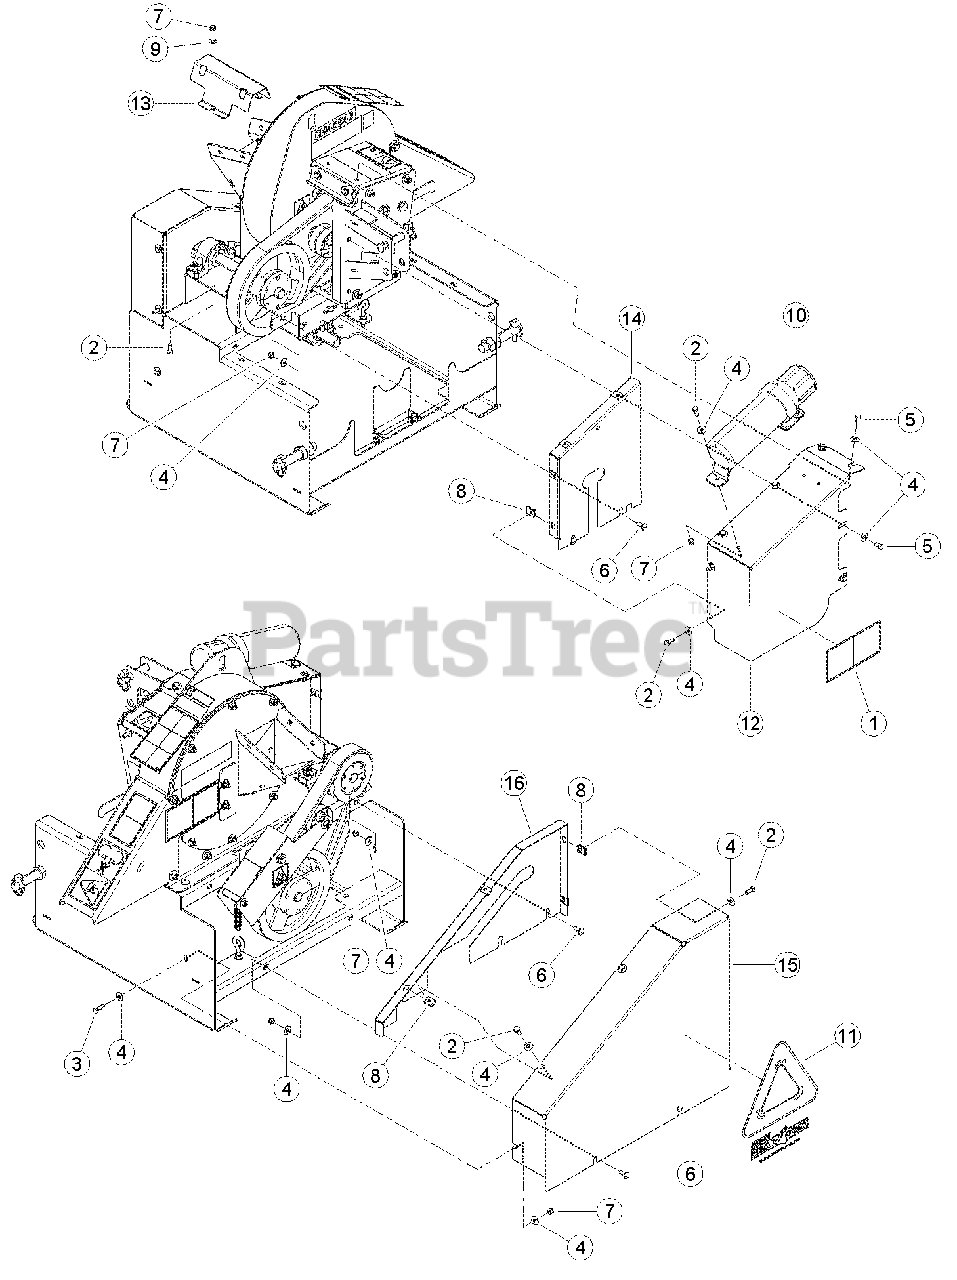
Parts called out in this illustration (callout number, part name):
1	DECAL, PTO DANGER ISO
2	BOLT, 5/16 X 3/4 HEX HD GR5 ZP
3	BOLT, 5/16 X 1 HEX HD GR5 NC ZP
4	WASHER, 5/16 FLAT ZP
5	BOLT, 5/16 X 5/8 HEX HD GR5 ZP
6	BOLT, 5/16 X 7/8 CRG GR5 NC ZP
7	NUT, 5/16 NE NYLOCK ZP
8	NUT 5/16-18 TINNERMAN U-TYPE
9	WASHER, 5/16 SAE FLAT ZP
10	CONTAINER, MANUAL
11	DECAL, CHIP IT LARGE
12	SHIELD, FRONT BELT
13	SHIELD, JACKSHAFT
14	SHIELD, BACK BELT
15	SHIELD, FORWARD BELT
16	SHIELD, REAR BELT
